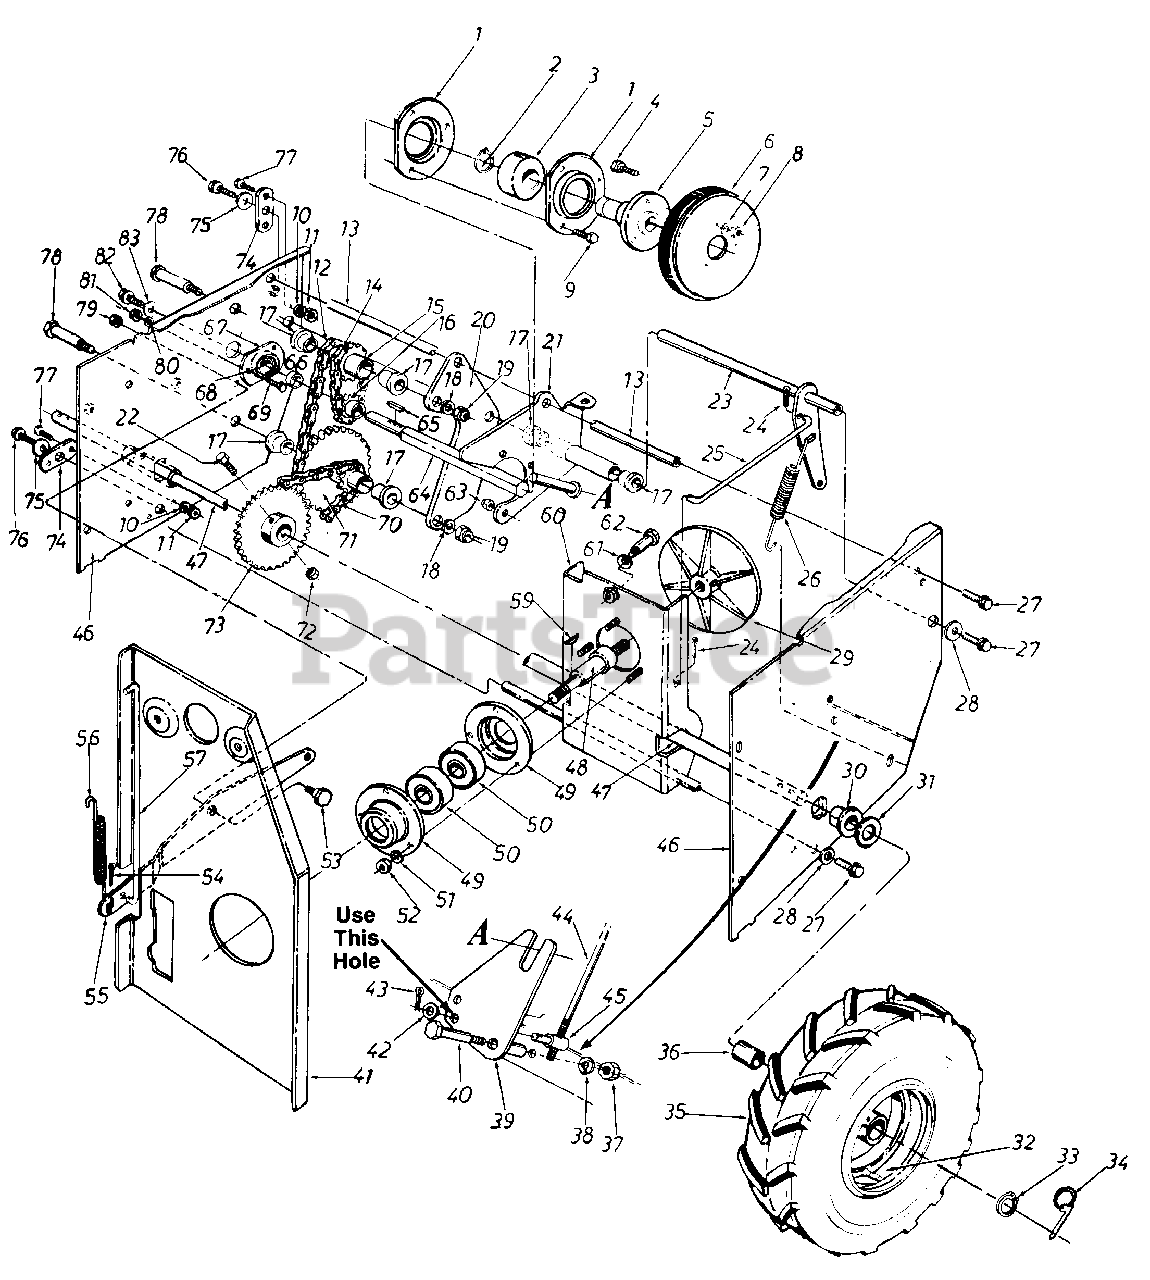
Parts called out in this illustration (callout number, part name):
1	Bearing Housing
2	Snap Ring-1.0" Dia.
3	Ball Brg. .25MM x 52MM x 15MM Thk.
4	Hex Sems Bolt 5/16-18 x .75" Lg.*
5	Friction Wheel Adapter
6	Friction Wheel Ass'y.
7	L-Wash. 5/16" I.D.*
8	Hex Nut 5/16-18 Thd.*
9	Hex Bolt 1/4-28 x .62" Lg.*
10	L-Wash. 1/4" I.D.*
11	Hex Nut 1/4-20 Thd.*
12	#41 Chain-1/2" Pitch x 43 Links
13	Sliding Support Axle
14	#41 Chain-1/2" Pitch x 19 Links
15	9 and 14 Teeth Sprocket Hub Ass'y.
16	8 Teeth Sprocket
17	Flange Bearing .63" I.D.
18	L-Wash. 3/8" I.D.-Heavy Duty
19	Hex L-Jam Nut 3/8-24 Thd.
22	Hex Bolt 5/16-24 x 1.75" Lg.*
23	Drive Clutch Brkt. Ass'y.
24	Inter. Cot. Pin 5/16" Dia.*
25	Drive Clutch Rod .31" Dia. x 7.38" Lg.
26	Extension Spring .73" O.D. x 4.31 " Lg.
27	Hex L-Bolt 5/16-18 x .62" Lg.
28	Fl-Wash. .345" I.D. x .75" O.D.
29	Aluminum Drive Plate
30	Flange Brg. w/Flats 1" I.D.
31	Fl-Wash. .62" I.D. x 1.25" O.D.
32	Tubeless Air Valve
33	Snap Ring 1" Shaft
34	Klick Pin Ass'y.
35	Wheel Ass'y. Comp. 16 x 4
36	Bearing 1.0" I.D. x 1.12" O.D. x 1.0" Lg.
37	Hex Jam Nut 3/8-16 Thd.
38	L-Wash. 3/8" I.D.*
41	Engine Brkt. Ass'y.
42	Fl-Wash. .344" I.D. x .62" O.D.
43	Cotter Pin 3/32" Dia. x .75" Lg. *
44	Shifting Rod
45	Adjustment Ferrule
46	Frame Ass'y.
47	Free Wheeling Axle
48	Drive Plate Spindle
49	Bearing Housing
50	Ball Brg. .787" I.D. x 1.85" O.D.
51	L-Wash. 5/16" I.D.*
52	Hex Nut 5/16-18 Thd.*
53	Shld. Bolt .625" Dia. x .170" Lg.
54	Inter. Cotter Pin 5/16" Dia.*
55	Auger Clutch Brkt.
56	Extension Spring .38" O.D. x 3.18" Lg.
57	Auger Clutch Rod .31" Dia. x 10.62" Lg.
59	#61 Hi-Pro Key 3/16" x 5/8" Dia.
62	Shld. Bolt
63	Hex Ins. Jam Nut 1/4-28 Thd.
64	Hex Shaft
65	#9 Hi-Pro Key 3/32" x 5/8" Dia.
67	Bearing Housing
68	Ball Bearing
69	Hex Bolt 1/4-20 x .62" Lg.*
70	#420 Chain .50" Pitch x 37 Links
71	9 and 32 Teeth Sprocket Hub Ass'y.
72	Hex L-Nut 5/16-24 Thd. (2 Req'd.)
73	28 Teeth Sprocket Hub Ass'y.
74	Pivot Axle Brkt.
75	Fl-Wash. .345" I.D. x .75" O.D.
76	Hex L-Bolt 5/16-18 x .62" Lg.
77	Hex Bolt 1/4-20 x .62" Lg.*
78	Sprocket Hub Tubing 1.880" Lg.
79	Hex Cent. L-Nut 3/8-16 Thd.
80	L-Wash. 1/4" I.D.*
81	Hex Nut 1/4-20 Thd.*
82	Hex L-Bolt 5/16-18 x .62"
83	Fl-Wash. .345" I.D. x .75" O D
